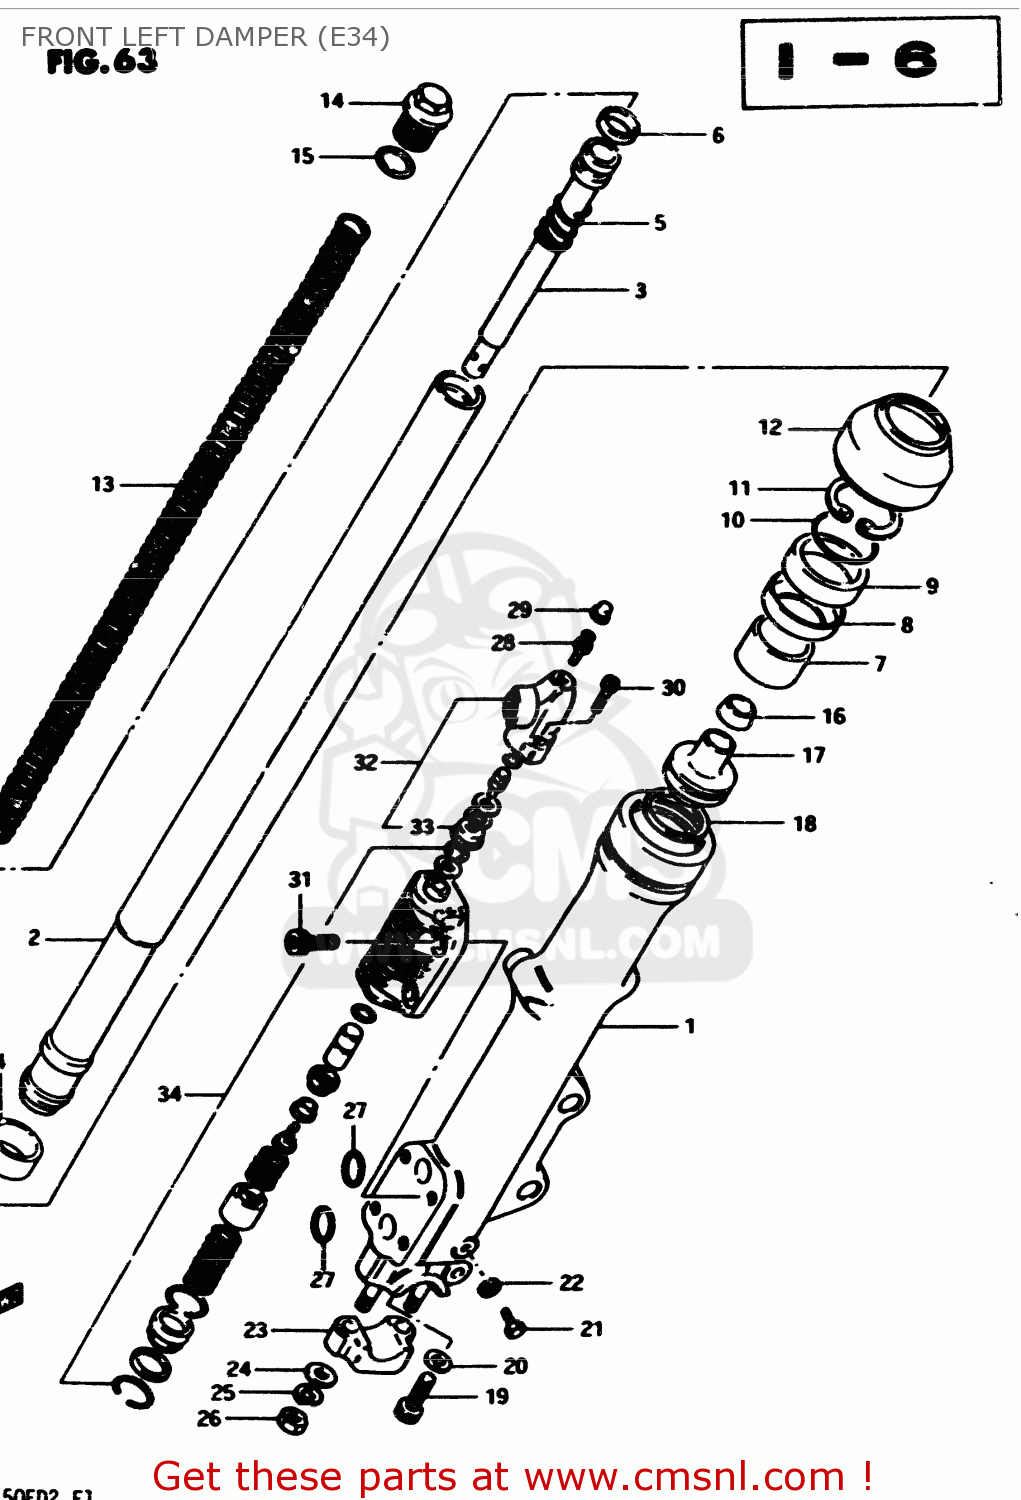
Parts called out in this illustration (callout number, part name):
1	OUTER TUBE LH
2	TUBE,FORK INNER,L
3	CYLINDER, LH
4	BUSH
5	SPRING,REBOUND
6	RING,PISTON
7	BUSH,GUIDE
8	SPACER,OIL SEAL
9	OIL SEAL,FRONT FORK
10	RING,BACKUP
11	RING,OIL SEAL STOPPER
12	DUST SEAL
13	SPRING,FR.FORK
14	BOLT
15	O RING
16	VALVE,OIL LOCK PIEACE
17	PIECE,OIL LOCK
18	RING, PISTON
19	BOLT(8X27)
20	GASKET (NAS)
21	BOLT
22	GASKET,DRAIN,PLUG (NAS)
23	HOLDER,AXLE
24	WASHER
25	LOCK WASHER
26	NUT
27	O RING,FR FORK
28	BREATHER
29	CAP
30	BOLT
31	BOLT
32	MODULATOR PARTS SET,FRONT
33	SEPARATOR,FRONT FORK MODULATOR
34	MODULATOR VALVE SET
